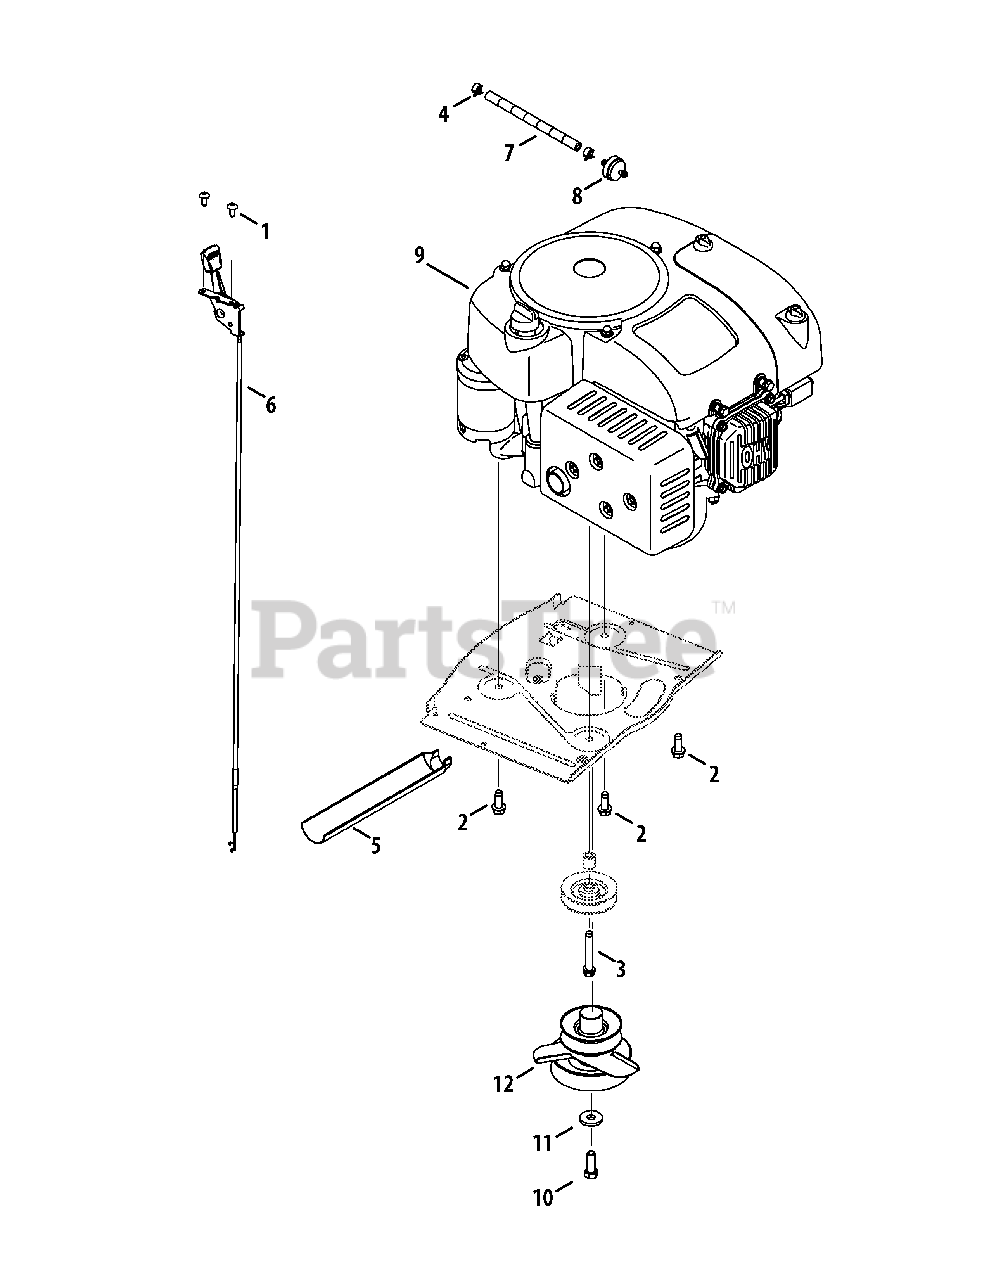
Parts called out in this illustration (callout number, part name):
1	Tap Screw, 1/4-20, 0.500
2	Tap Screw, 3/8-16, 1.000
3	Tap Screw, 3/8-16, 2.250
4	Hose Clamp, .490 DIA.
5	Oil Drain Sleeve
6	Throttle/Choke Cable 31 Lg.
7	Low Permeation Fuel Line, 1/4
8	Fuel Filter, 1/4"
9	Engine
10	Hex Head Screw, 7/16-20, 1.250
11	Flat Washer, .450 X 1.250 X .164
12	Engine Pulley, 4.46 dia./3.39 dia.
